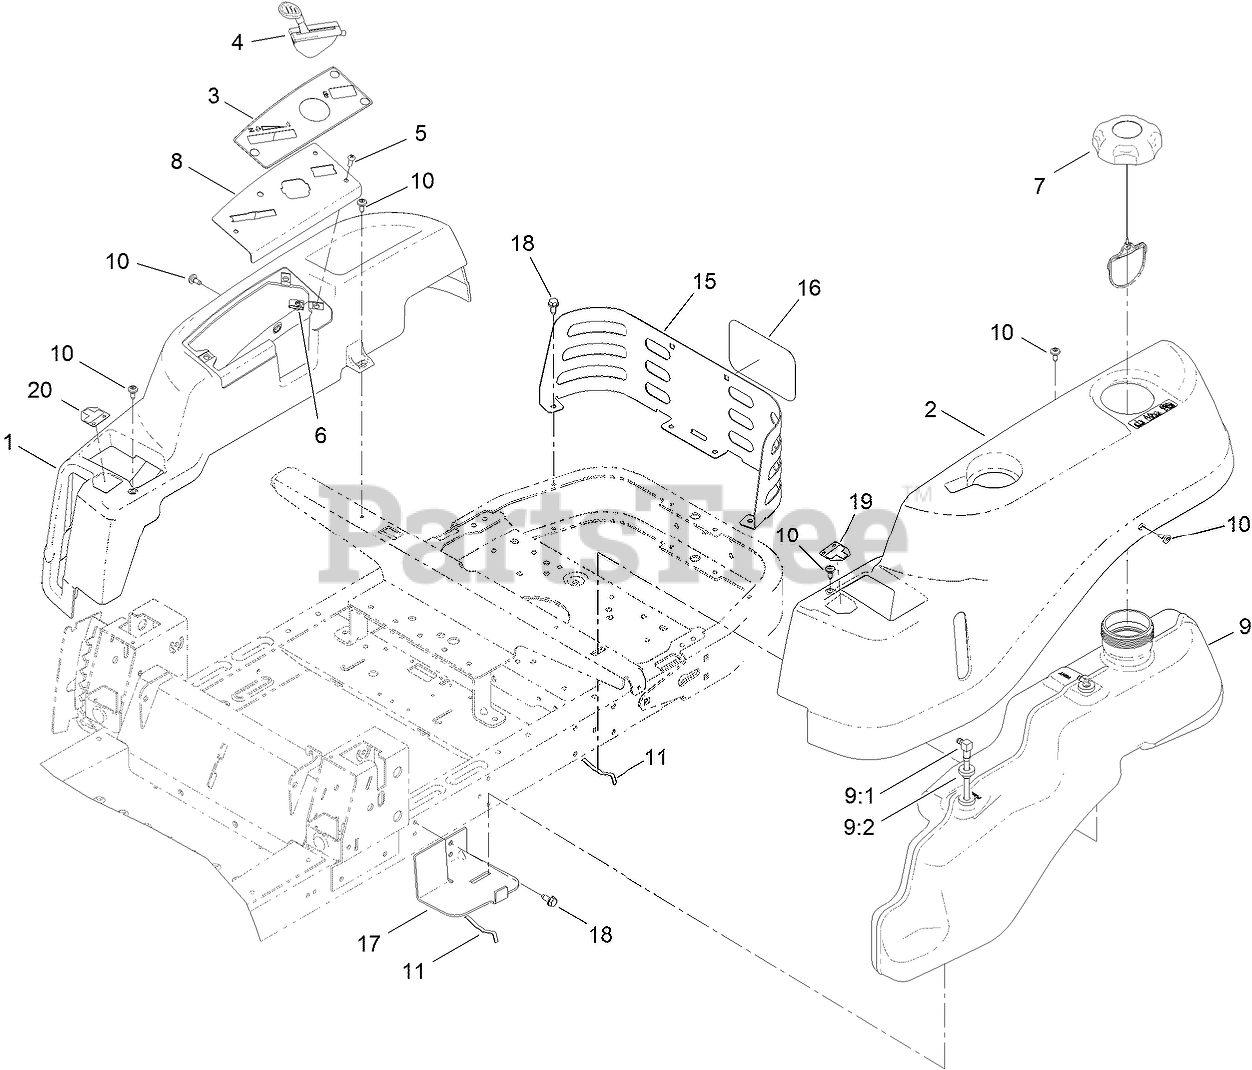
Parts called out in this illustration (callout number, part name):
1	POD-RH
2	POD-LH
3	DECAL-PANEL, CONTROL
4	CABLE-THROTTLE AND CHOKE
5	SCREW-PRH
7	CAP-FUEL, RATCHETING
8	PLATE-CONTROL
9	FUEL TANK ASM
9:1	CONNECTOR-ELBOW, 90 DEG
9:2	BUSHING
10	SCREW-SHOULDER
11	SPRING
15	GUARD-REAR
17	SUPPORT-TANK, FRONT
18	SCREW-HWHTF
19	DECAL-CONTROL LEVER, LH
20	DECAL-CONTROL LEVER, RH
